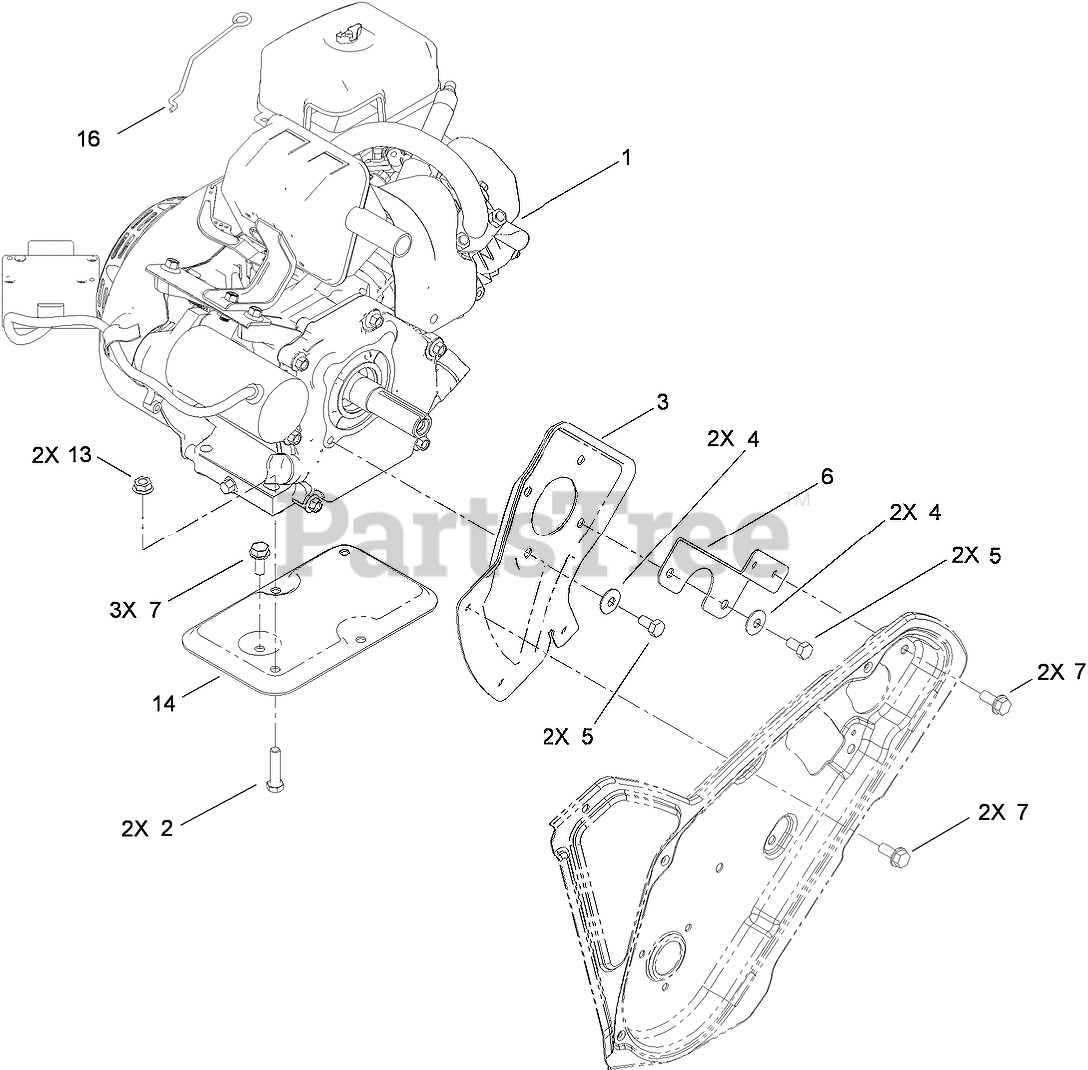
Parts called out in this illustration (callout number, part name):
1	ENGINE-LC168FDS-1
2	SCREW-HH
3	PLATE-ENGINE, PTO
4	WASHER-BELLEVILLE
5	SCREW-HHF
6	SUPPORT-ENGINE, SIDE
7	SCREW-HWHTF
13	NUT-HF
14	SUPPORT-ENGINE
16	LINK-KNOB, CHOKE
